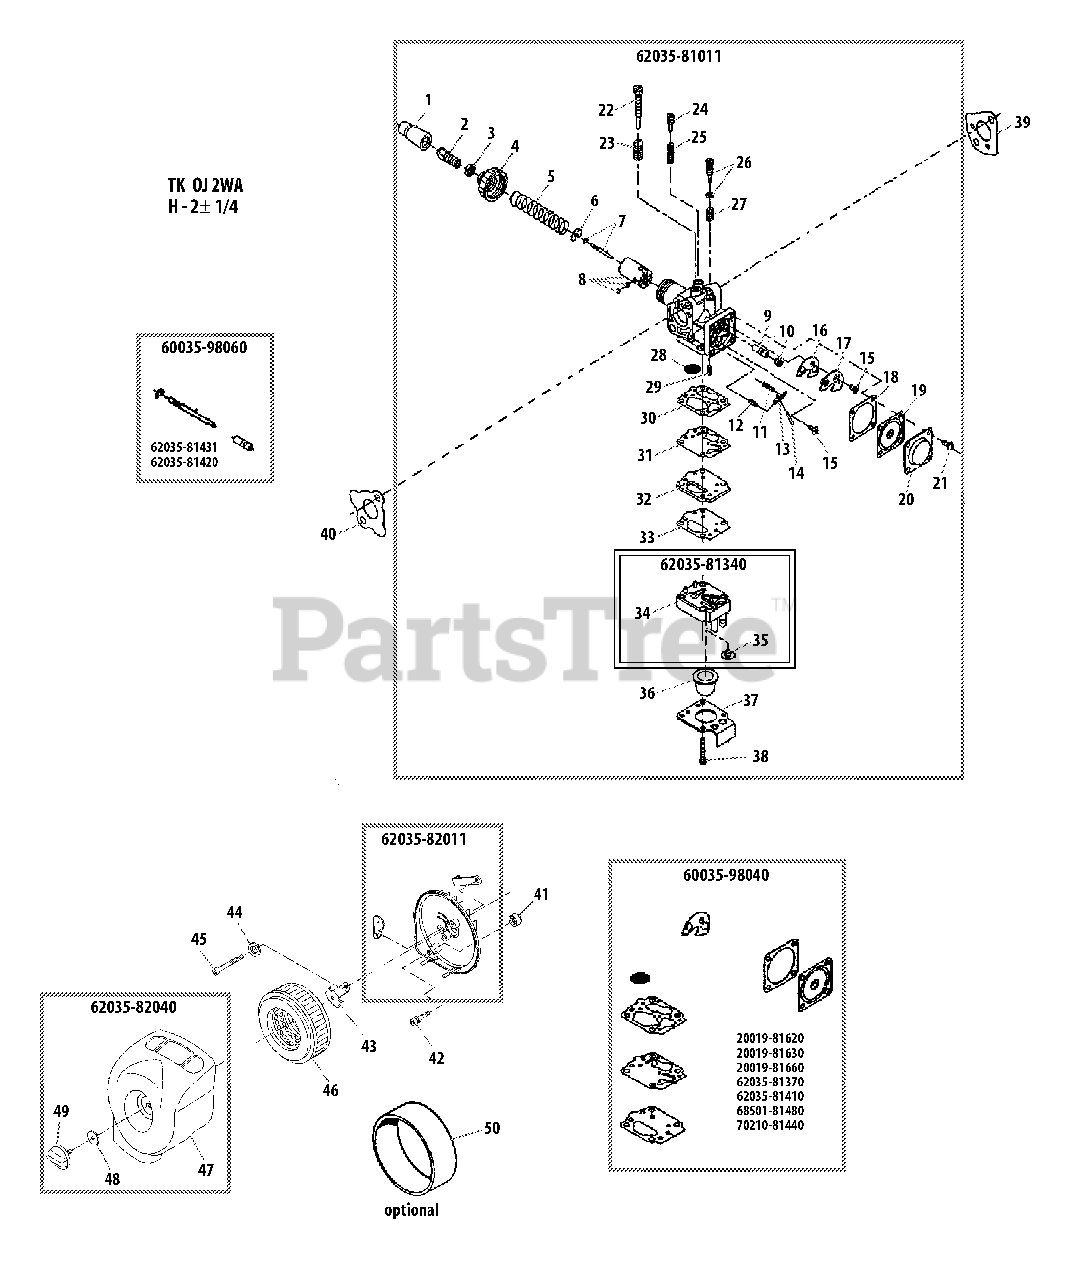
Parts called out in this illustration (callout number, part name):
1	GROMMET
2	ADJUSTER, CABLE
3	NUT, LOCK
4	CAP, CARBURETOR
5	SPRING, THROTTLE
6	WASHER
7	NEEDLE, JET
8	VALVE, THROTTLE
9	NEEDLE, JET
10	HOLDER, MAIN JET
11	SPRING
12	VALVE, INLET NEEDLE
13	LEVER, METERING
14	PIN, METERING LEVER
15	SCREW M3×8
16	PACKING
17	PLATE
18	GASKET, DIAPHRAGM
19	DIAPHRAGM, METERING
20	COVER, DIAPHRAGM
21	SCREW M3×8
22	SCREW, IDLE ADJUST
23	SPRING
24	SCREW, SLOW AIR
25	SPRING
26	SCREW, MAIN ADJUST
27	SPRING
28	SCREEN, FUEL INLET
29	SPRING, COIL
30	GASKET, PUMP
31	DIAPHRAGM, FUEL PUMP
32	PLATE, PUMP
33	GASKET, FUEL PUMP
34	COVER, PUMP
35	VALVE
36	BULB, PURGE
37	PLATE, PUMP
38	SCREW
39	GASKET, INTAKE
40	GASKET, INTAKE
41	INSULATOR
42	BOLT M5×40
43	PLATE, PREVENT
44	WASHER, SPRING 5
45	BOLT
46	FILTER, AIR
47	COVER, AIR FILTER
48	WASHER
49	THUMBSCREW
50	PRE-FILTER, FOAM
60035-98040	GASKET / DIAPHRAGM KIT
60035-98060	NEEDLE/JET KIT
62035-81011	CARBURETOR
62035-81340	COVER ASSY, PUMP
62035-82011	CASE ASSY, AIR FILTER
62035-82040	AIR FILTER COVER ASSY
